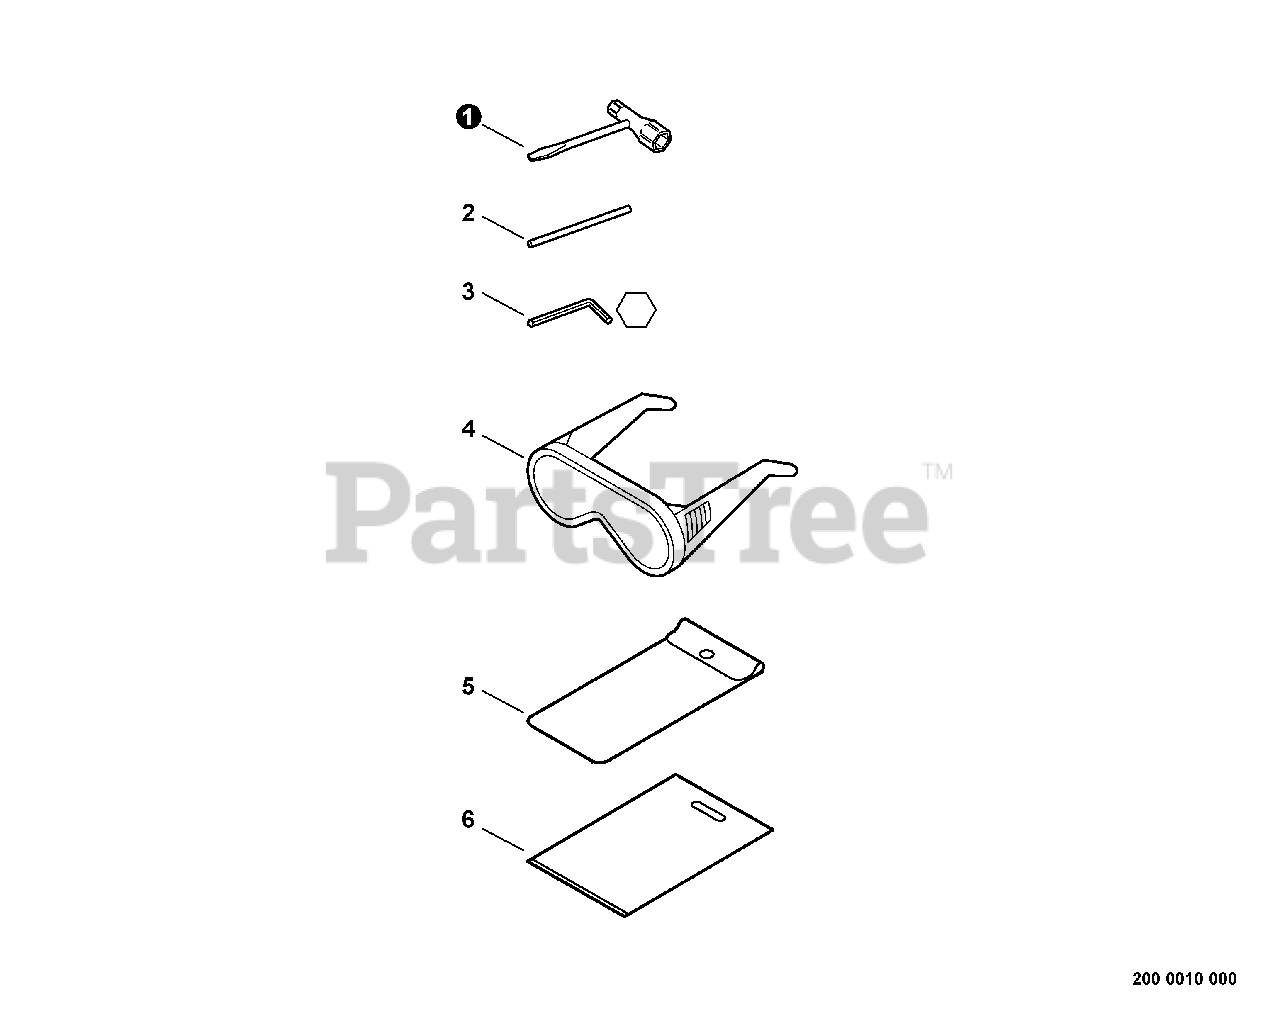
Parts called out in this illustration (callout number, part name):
1	T-WRENCH - 17X19mm
2	ROD, LOCKING - 5X120mm
3	HEX KEY - 4mm
4	GOGGLES
5	BAG, TOOL
6	BAG, TOOL
